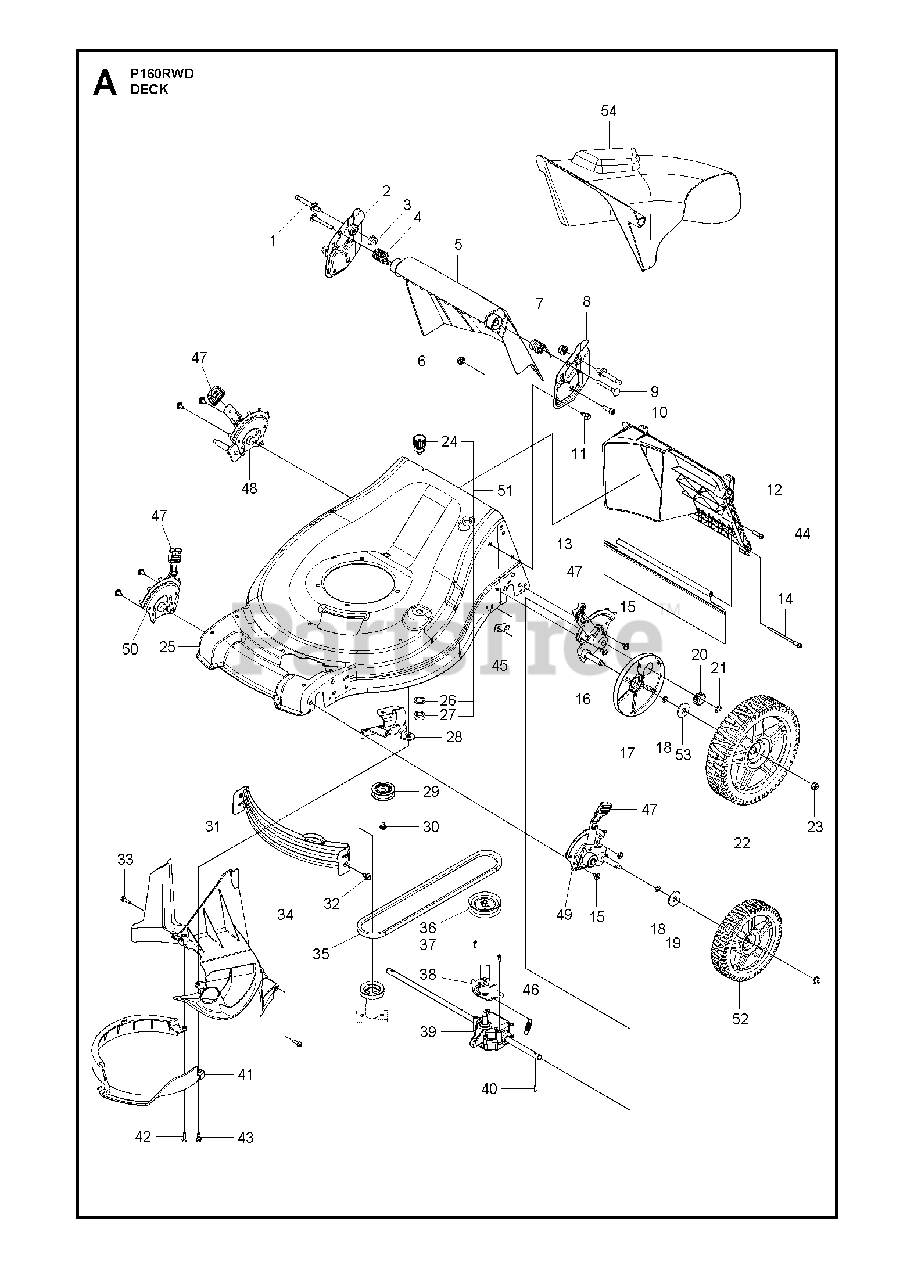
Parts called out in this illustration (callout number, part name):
1	Hand Pivot Bolt, 3125-18.21Eff
2	BRACKET.HANDLE.ADJ.21EFF.RH479
3	Flange Nut, Serrat.3125-18.5625
4	SPRING.RH.DOOR.21 EFF
5	DOOR.REAR.21 EFF.BLACK
6	Flange Nut, 3/8-16 Zinc
7	SPRING.LH.DOOR.21 EFF
8	BRACKET.HANDLE.ADJ.21EFF.LH479
9	Pivot Door Bolt, .375-16 21Eff
10	Screw, Hi-Lo,5/16-14 X T-45
11	BOLT.5/16HEX.WHS.HD
12	Insert, Rear 21 Eff
13	Skirt, Rear 21" Eff
14	Screw, Hi-Lo.5/16-14 X 4.10
15	SCREW
16	ADJUSTER.4PT.21EFF.LR
17	Dust Cover, AW/RW HW CONS
18	O-RING..070X.487.NEOPRENE
19	WASHER FLUT
20	Pinion 16 Teeth Hw Awd Rear
21	E-RING 7/16 RE
22	WHEEL.11X2.R3.5SP.AW/RW.BU.460
23	NUT.HEX.FLANGE.3/8-16.LOCKNUT
24	FITTING, HOSE, WATER WASHOUT
25	KIT.HSG.21EFF.RGD.NC.WO.613.SY
26	WASHER.LOCK.INTERNAL.TOOTH
27	LOCKNUT.HEX.WITH.O-RING
28	BRACKET.IDLER.RWD.BZP
29	Idler Pulley, RWD Double Seal
30	SCREW
31	Front Baffle, 21" Eff
32	BOLT.5/16HEX.WHS.HD
33	Screw, Hi-Lo.13-16 X .750.375 X drv
34	Baffle Cover, 21 Eff
35	Belt, 21EFF RWD
36	SCREW M3X8 MACHINE SCREW
37	SCREW
38	Trans Belt Keeper Bracket
39	Transmission, Awd Rear 21Eff
40	PAWL, DRIVE
41	Stripper Ring, 21 Eff
42	Screw, Hi-Lo.13-16 X .750.375 X drv
43	Shoulder Bolt, 1/4-20 Trilob
44	Screw, Hi-Lo,5/16-14 X T-45
45	STRAP.PLATE ATTACH.21 EFF.GLV
46	SPRING.RETURN.AUTO.
47	SELECTOR KNOB
48	ADJUSTER.4PT.21EFF.RR
49	Adjuster, 4Pt 21Eff Lf/Rr Bu Bk
50	Adjuster, 4Pt 21Eff Rf/Lr Bu Bk
51	KIT.WASH-OUT.PORT
52	WHEEL.8X1.75.CF5SPK.RAD3.GRAY
53	WASHER PM
54	Discharge Chute, 21" EFF HW
